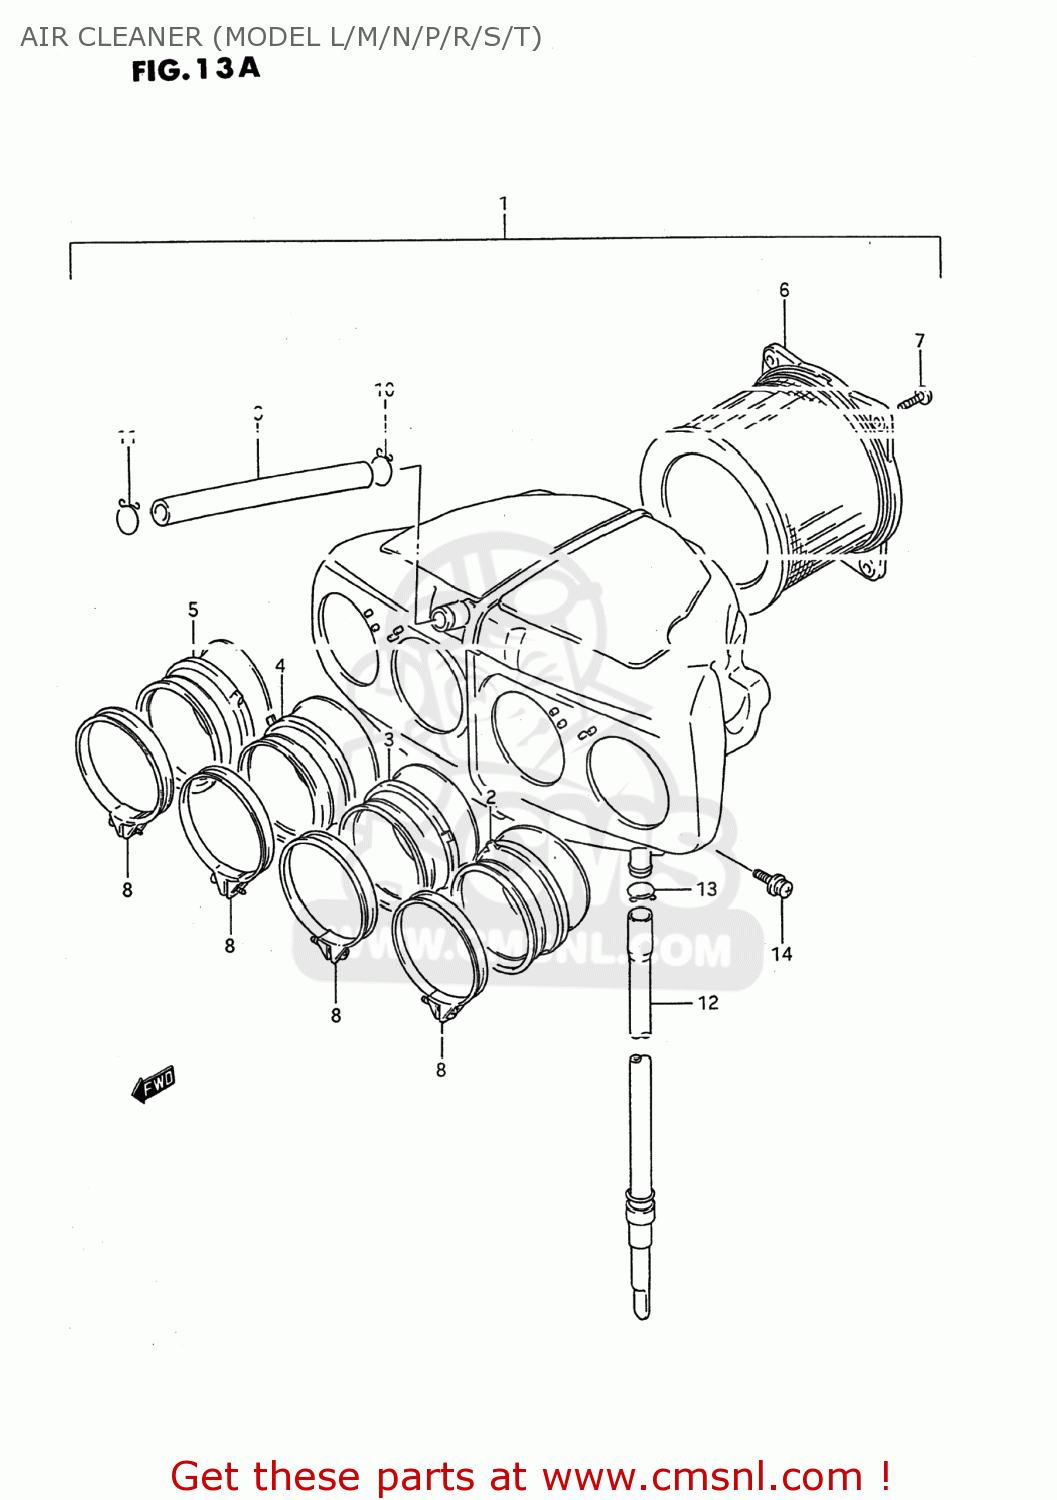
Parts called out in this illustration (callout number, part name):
1	CLEANER ASSY, AIR
2	TUBE,OUTLET,L
3	TUBE,OUTLET ML
4	TUBE,OUTLET MR
5	TUBE,OUTLET,R
6	FILTER ASSY
7	SCREW 5X12
8	CLAMP
9	TUBE,BREATHER
10	CLIP
11	CLIP
12	TUBE,DRAIN
13	CLIP
14	SCREW
